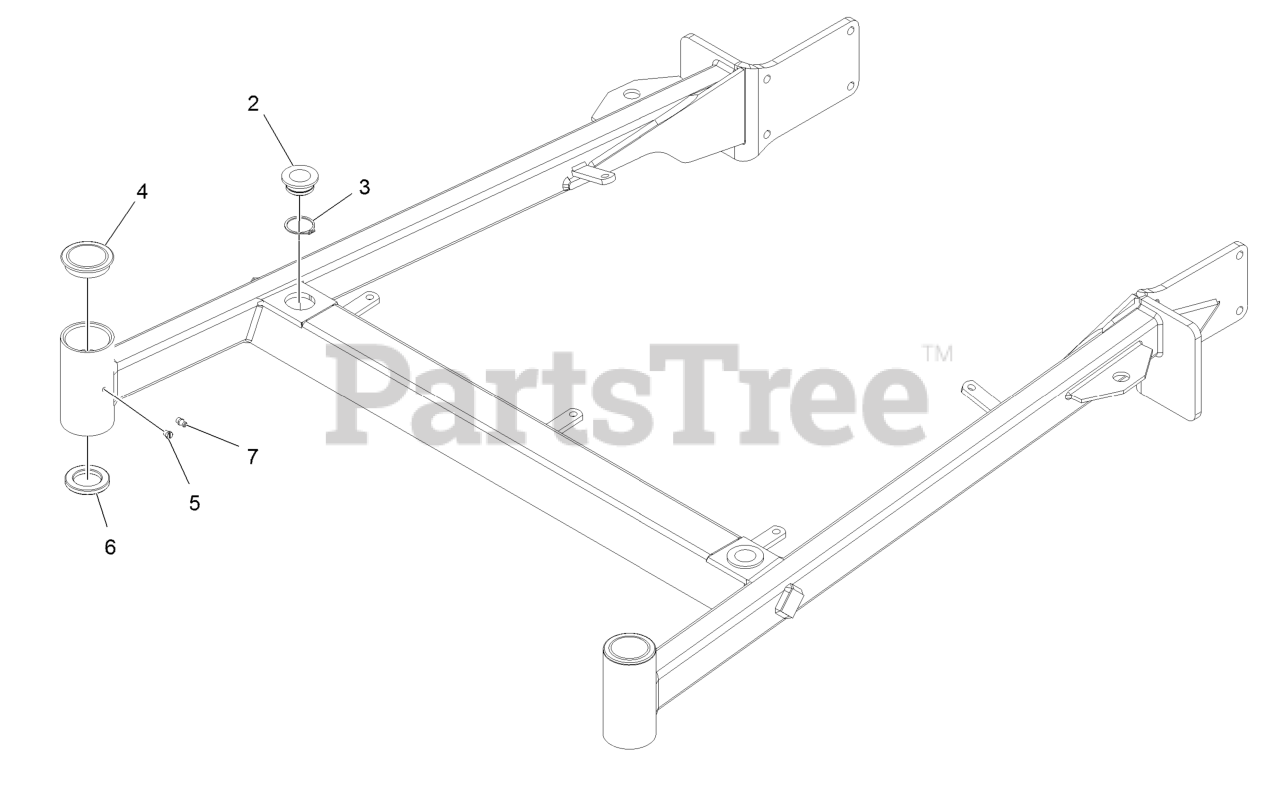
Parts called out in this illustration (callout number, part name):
2	BUSHING-DECK
3	RING-RETAINING
4	CAP-GREASE
6	SEAL-GREASE
7	FITTING-GREASE
